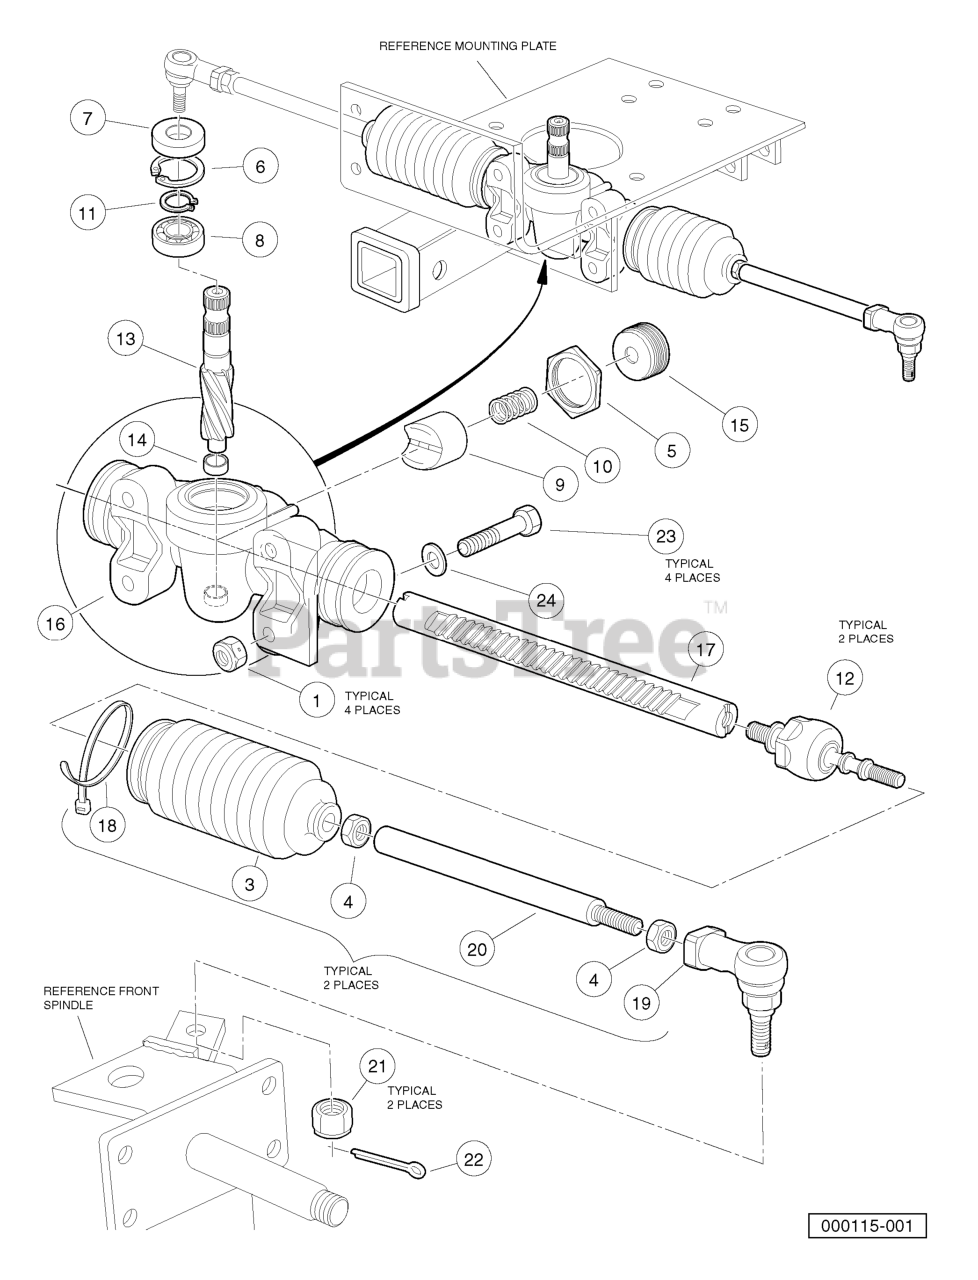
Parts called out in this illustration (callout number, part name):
1	LOCKNUT, DIMPLED
2	RACK & PINION STEERING GEAR
3	BELLOWS, LONG
4	12MM HEX NUT
5	RACK SCREW LOCKNUT
7	SEAL, STEERING PINION DUST
8	BEARING BALL
9	SUPPORT YOKE
10	RACK GUIDE PRESSURE SPRING
11	C-TYPE STOP RING
12	INNER BALL JOINT ASM
19	TIE ROD END
21	LOCKNUT, M12-1.25 NYLON
22	COTTER PIN
23	SCREW, 3/8-16 X 1.5 HX HD CAP
24	WASHER, 3/8 FLAT
